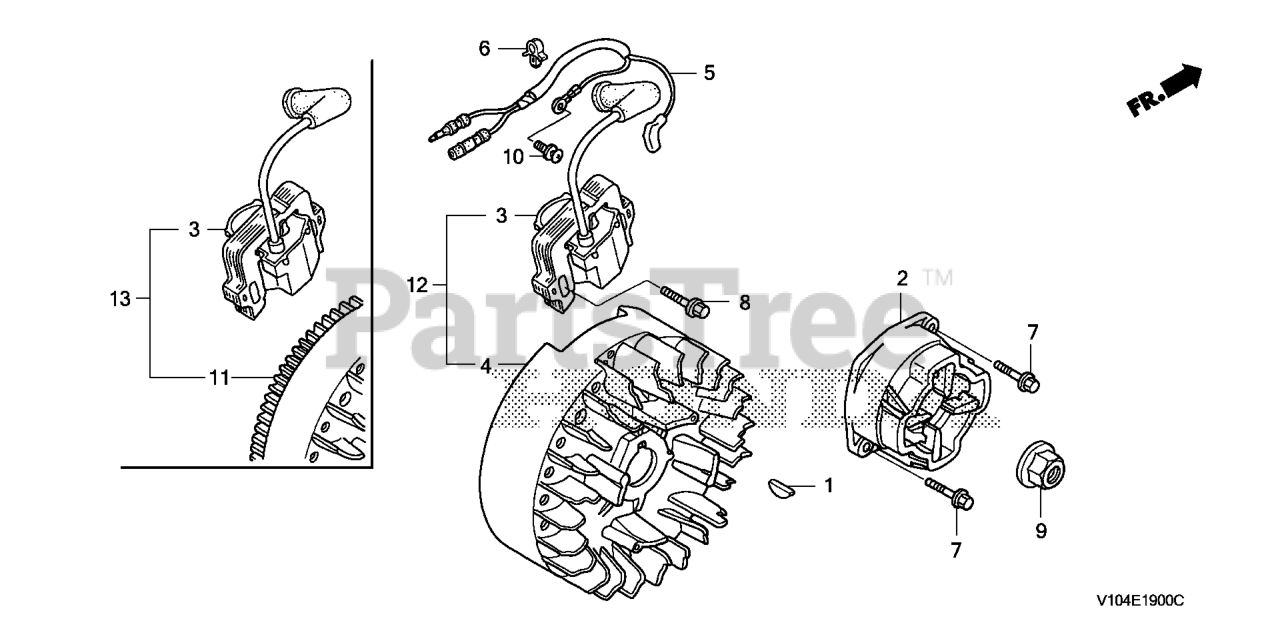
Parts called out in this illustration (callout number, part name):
1	KEY, SPECIAL WOODRUFF (25X18)
3	COIL ASSY., IGNITION (FENGLONG)
5	WIRE, STOP SWITCH
6	CLIP, BRAKE PIPE (A) (FOR NEUTRAL SWITCH)
8	BOLT, FLANGE (6X23)
9	NUT, FLANGE (14MM)
10	SCREW-WASHER (5X8)
11	FLYWHEEL COMP.(TEC) (USE FOR IGN. COIL OF TEC)
